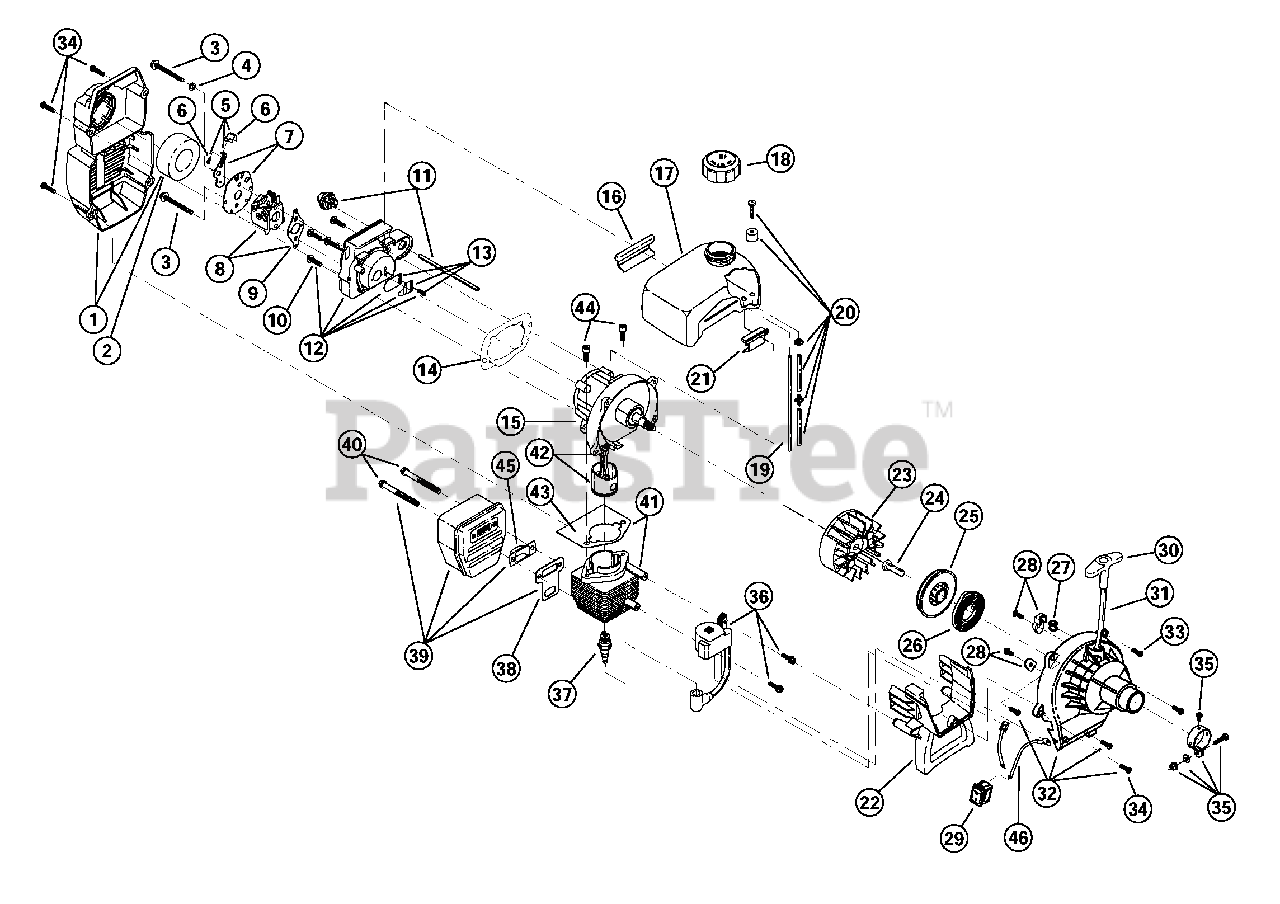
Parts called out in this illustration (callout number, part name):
1	Air Cleaner/Muffler Cover Assembly
2	Air Cleaner Filter
3	Carburetor Mounting Screw Assembly
4	Wavey Washer
5	Choke Lever Assembly
6	Choke Knob and Screw
7	Choke Lever and Plate
8	Carburetor Assembly
9	Carburetor Gasket
10	Carb Mount Screw
11	Primer and Hose Assembly
12	Carb Mount Assembly
13	Reed Assembly
14	Carburetor Mount Gasket
15	Crank Case Service Assembly
16	Rear Mounting Pad
17	Fuel Tank Assembly
18	Fuel Cap Assembly
19	Fuel Return Line
20	Fuel Line Assembly
21	Front Mounting Pad
22	Shroud Extension and Stand
23	Flywheel Assembly
25	Recoil Pulley Assembly
26	Recoil Spring
27	Rope Guide
28	Pulley Retainer Assembly
29	Momentary Switch
30	Pull Handle
32	Starter Housing Assembly
33	Housing Screw
34	Cover Screw
35	Upper Clamp Assembly
36	Governed Module Assembly
37	Spark Plug
38	Exhaust Gasket
39	Muffler Assembly
40	Muffler Mounting Bolt Assembly
41	Cylinder Assembly
42	Piston and Rod Assembly
43	Cylinder Gasket
44	Cylinder Bolt
45	Spark Arrestor
46	Lead Wires
